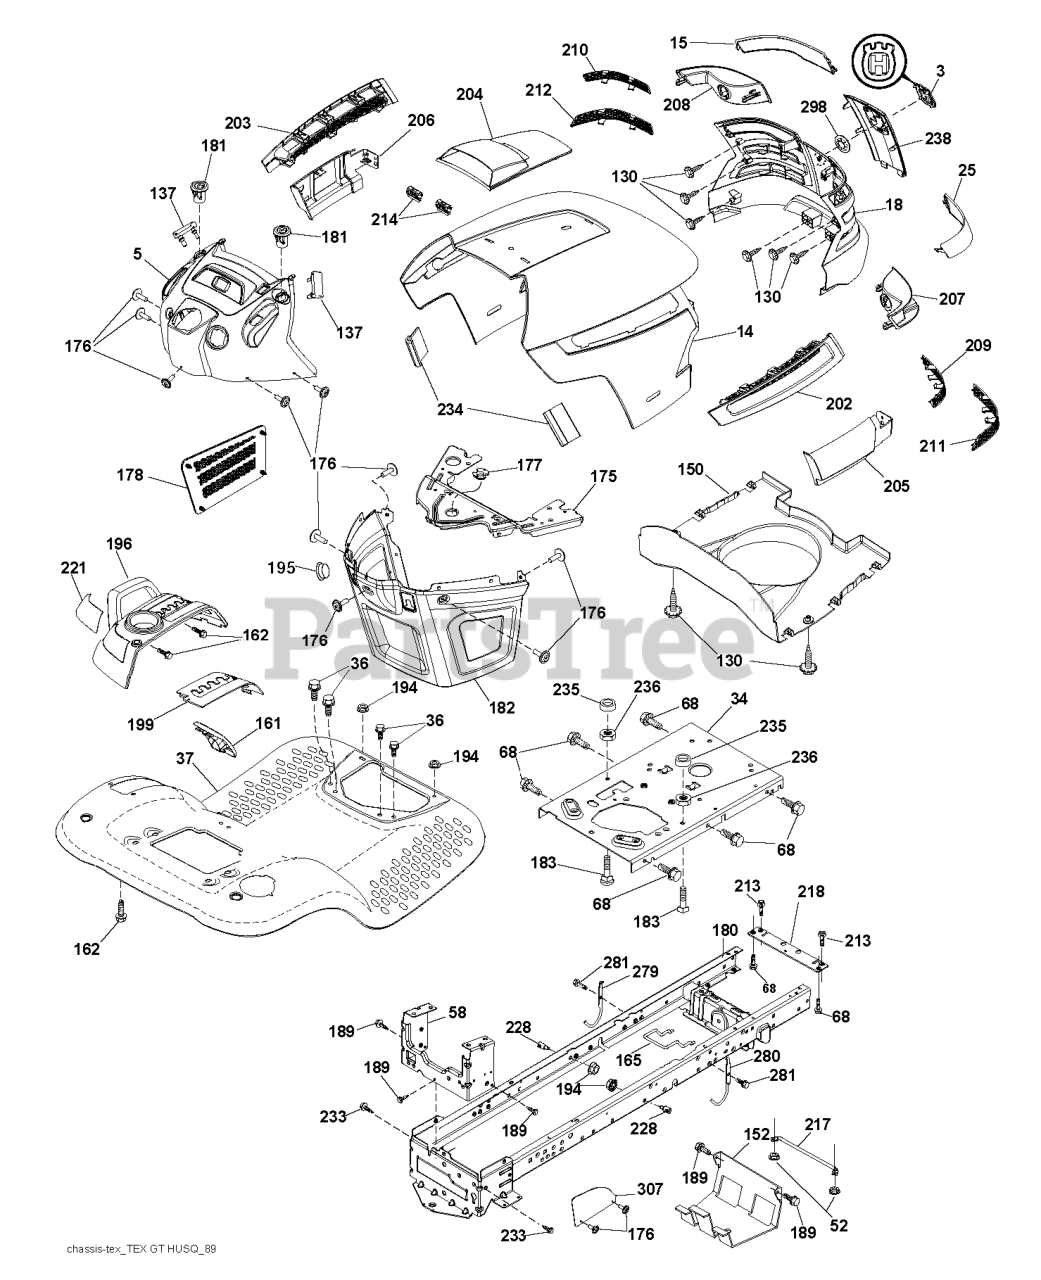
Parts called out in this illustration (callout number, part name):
3	RP LOGO
14	HOOD
15	LENS.LH.TEX.GT.HUSQ.CL
18	GRILL.ASM.HUSQ.TG/CRD.W/TRIM
25	LENS.RH.TEX.GT.HUSQ.CL
34	PLATE.ENGINE.WELDED.CHASSIS
36	SCREW 5/16"
37	FENDER.PNT.TX.GT.CH/FW.ORANGE
52	LOCKNUT
58	DRAWBAR.UPPER.2PC,LRG.FENDER
68	Screw 5/16-18 x 1/2 Hex, Self Tapping 5/16-18 x 1/2
130	SCREW.#10 X 0.750.BOS
137	BUMPER DASH
150	AIR.DUCT.HOOD.TEX.GT.HUSQ
152	SHIELD.BROWNING.W/TEX
161	CONSOLE.FUEL.WINDOW.HU
162	SCREW.HI-LO.CONSOLE
165	SUPPORT.TANK.REAR.W/TEX
175	PLATE.CROSSMEMBER.HUSQ
176	SCREW.#10-24X5/8.RN.QU
177	BUSHING, STEERING
178	CARGO.ASM.NET.TXGT.W/C
180	CHASS.WLDMNT.TL.12GA/2P.48/54
181	BUSHING.MNT.FEND.CRGO.
182	DASH.LOWER.COMMON.12V.ADAPTOR
183	BOLT.5/16-18X1-1/4 FULL THD
189	SCREW
194	NUT LOCK HEX FLANGE 5/16-18
196	RP CONSOLE.ASM.DECKLFT.W/
199	PLATE.DECK.LIFT.HUSQVARNA.GT
202	VENT.SIDE.HOOD.HUSQ.RH.GREY
203	VENT.SIDE.HOOD.HUSQ.LH.GRAY
204	HOOD VENT
205	SKIRT.HOOD.SIDE.HUSQ.RH.GREY
206	SKIRT.HOOD.SIDE.HUSQ.LH.GREY
207	BEZEL.RH.TEX.GT.HUSQ
208	BEZEL.LH.TEX.GT.HUSQ
209	INSERT.HEX.GRILL.HUSQ.GREY
210	INSERT.HEX.GRILL.HUSQ.
211	INSERT.HEX.GRILL.HUSQ.
212	INSERT.HEX.GRILL.HUSQ.
213	BOLT
214	CLIP.RETAINER.TINNER.
217	ROD.PIVOT.HOOD
218	X-PIECE.HOOD.STOP.NON/
221	REFLECTOR.LH.TEX GT HU
228	STUD.FASTNER.W/ANTI-ROTATE
233	BOLT.SHOULDER
234	BUMPER.HOOD.TEX.HUSQVARNA
235	SPACER FENDER
236	NUT.CENTERLOCK.5/16-
238	TRIM.HUSQ.TG/CRD.SERVICE
279	ROD UPSTOP
280	ROD UPSTOP
281	SCREW 3/8-16X1
298	NUT PUSH M
307	SHIELD UPPER PEDAL
